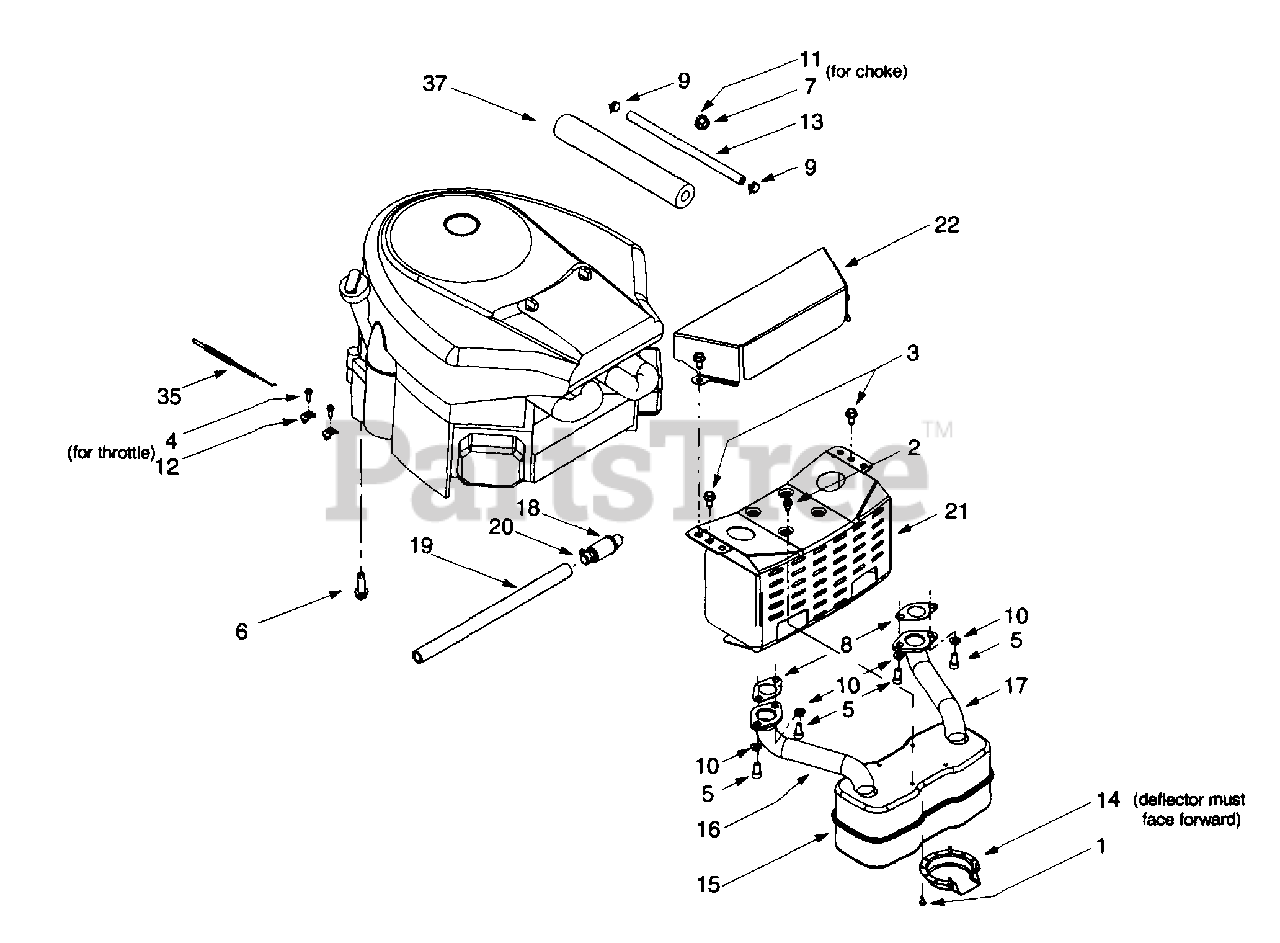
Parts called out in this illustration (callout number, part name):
1	Self-tapping Screw, #8-32 x .375
2	Self-tapping Screw, 1/4-20 x .5
3	Self-tapping Screw, 5/16-18 x .625
4	Screw, #10-32 x .625
5	Socket Cap Screw, 5/16-18 x .625
6	Self-tapping Screw, 3/8-16 x 1.25
7	Hex Nut, 3/8-16
8	Exhaust Gasket
9	Hose Clamp
10	Lock Washer, 5/16
11	Flat Washer, .406 x .875 x .059
12	Casing Clamp
13	Fuel Line Hose
14	Muffler Deflector
15	Muffler, Twin Inlet
16	RH Exhaust Pipe
17	LH Exhaust Pipe
18	Oil Drain Valve
19	Oil Drain Hose
20	Oil Drain Cap
22	Engine Heat Shield
35	Throttle Cable
37	Foam
